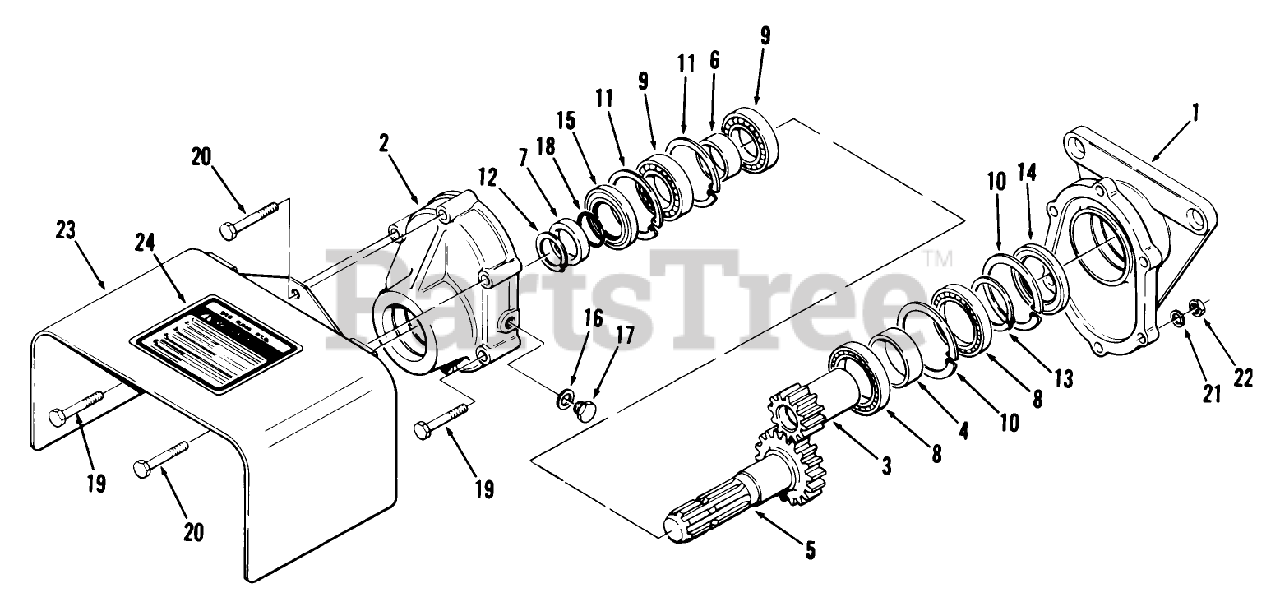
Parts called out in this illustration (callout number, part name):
2	Case Half-Rear
16	Gasket
23	Drive Shield
